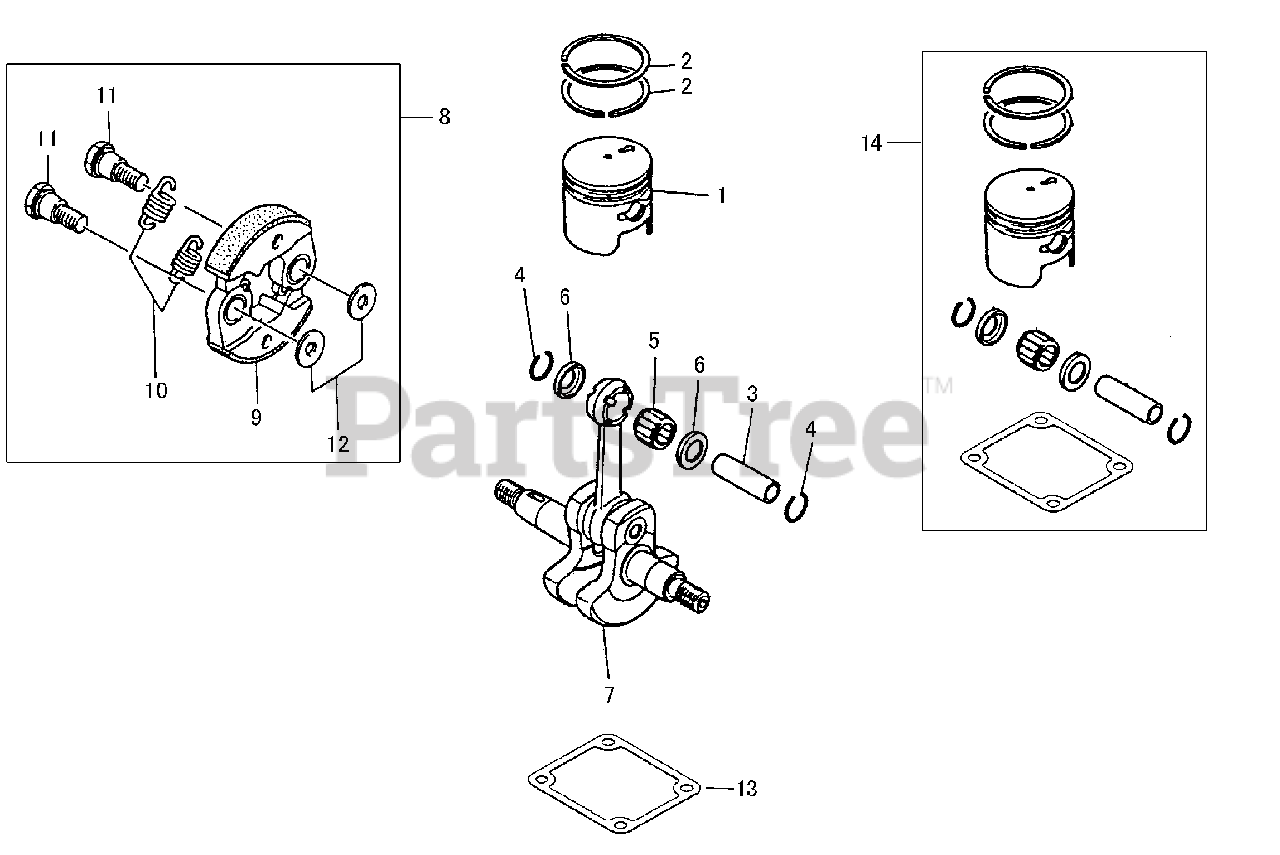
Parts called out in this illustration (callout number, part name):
1	PISTON
2	RING, PISTON
3	PIN, PISTON
4	RING, RETAINING
5	BEARING, NEEDLE
6	WASHER, THRUST
7	CRANKSHAFT ASSY
8	CLUTCH SHOE ASSY
9	SHOE, CLUTCH
10	SPRING, CLUTCH
11	BOLT, CLUTCH
12	WASHER
13	GASKET, CYLINDER
14	PISTON KIT
